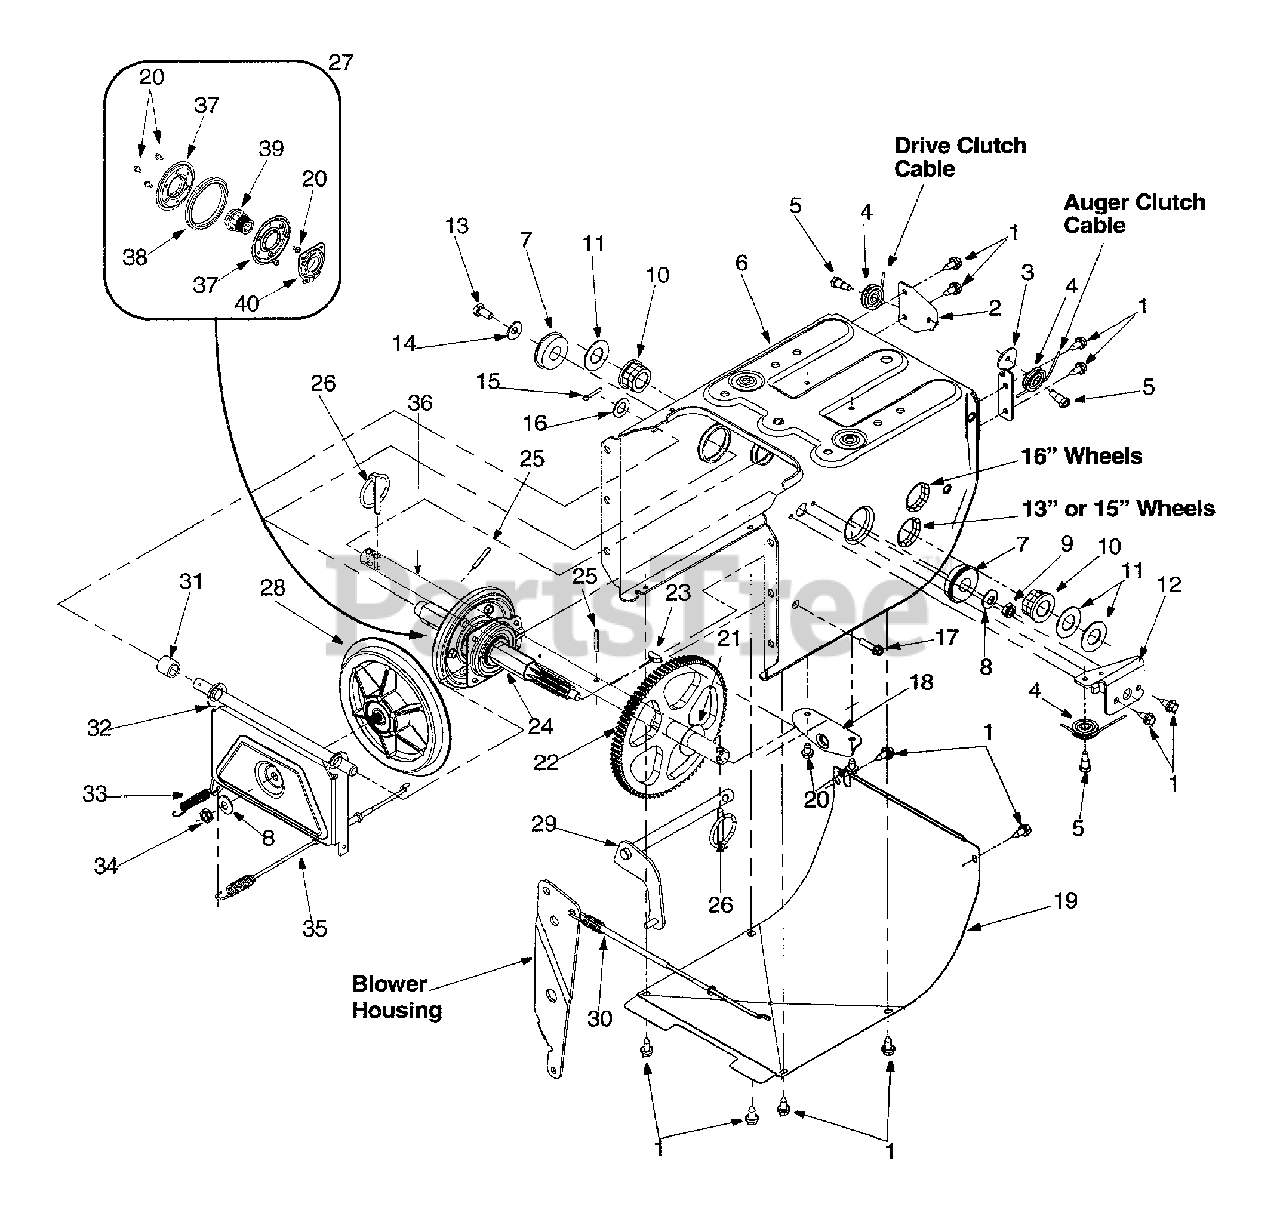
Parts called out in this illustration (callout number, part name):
1	Hex Screw
5	Hex Screw 1/4-28
8	Bell Washer
9	Lock Jam Nut
10	Hex Flange Bearing
11	Flat Washer
14	Bell Washer.340 ID x .872 OD
15	Cotter Pin
16	Flat Washer.536 ID x .930 OD
17	Hex Washer Screw 1/4-20
21	Flat Washer .760 ID x .50 OD
24	7-Tooth Shaft
25	Roll Pin
26	Klik Pin
27	Friction Wheel Assembly
28	Friction Disc Wheel
29	Wheel Shift Rod Assembly
30	Drive Cable
31	Spacer
34	Jam Nut 3/8-24
35	Drive Cable
36	Axle 13" Wheels
37	Friction Plate
38	Friction Wheel Rubber
39	Friction Wheel Hub
40	Friction Wheel Bearing
